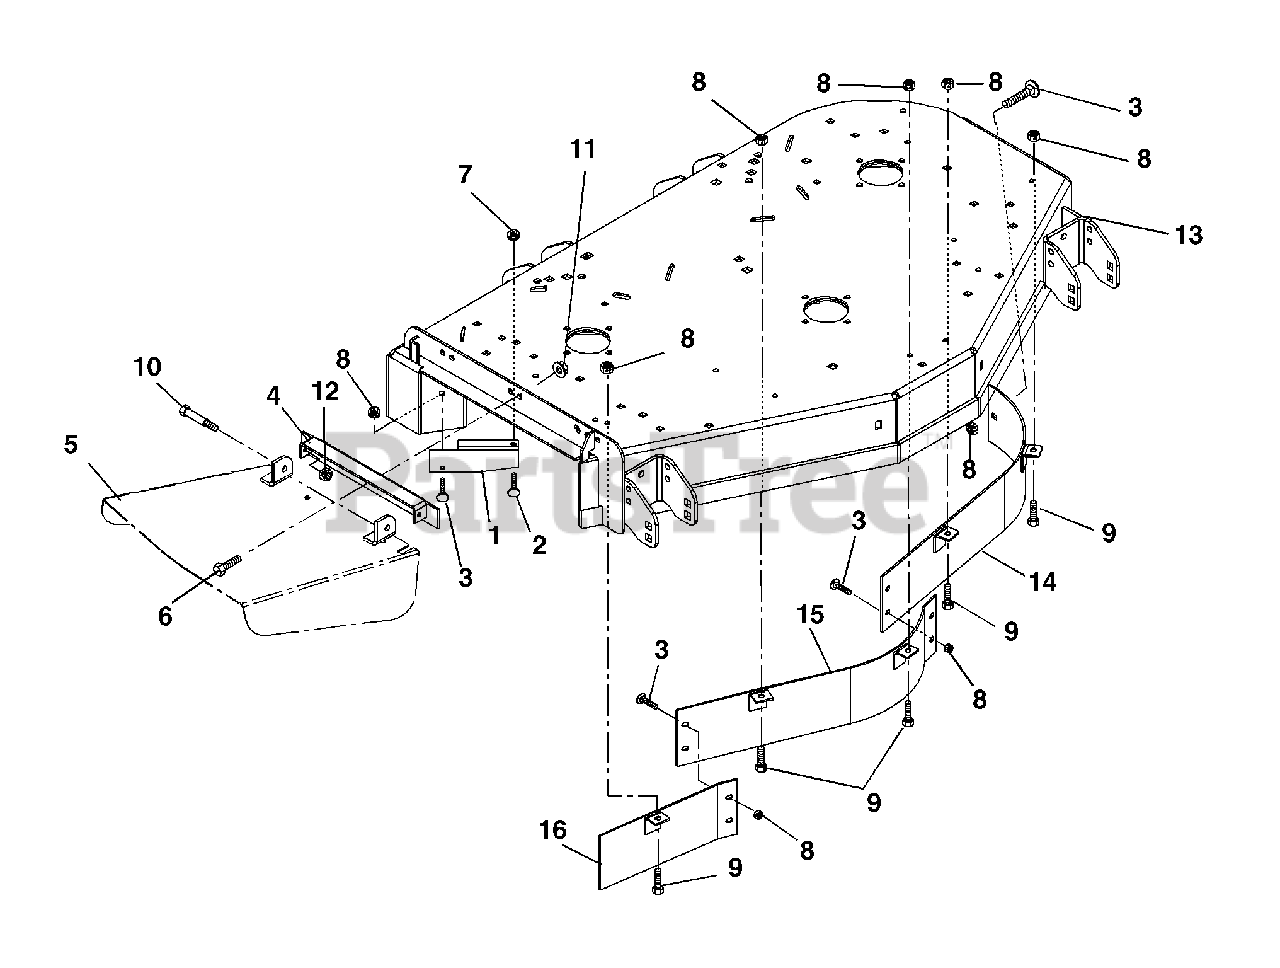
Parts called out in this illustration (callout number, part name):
1	Deflector- 60" (058, 060, 318, 319)
1	Deflector- 72" (059, 061)
2	Bolt-Round Head Square Neck .38-16 x .75 Grade 5
3	Bolt-Round Head Square Neck .31-18 x .75 Grade 5
4	Weldment, Discharge Chute Bracket
5	Chute-Discharge (058, 060, 318, 319)
5	Chute-Discharge (059, 061)
6	Bolt-Hex .38-16 x 1.00 Grade 5
7	Nut-Locking-Top-Flange .38-16
8	Nut, Locking-Top-Flange .31-18
9	Bolt, Hex .31-18 x .75 Grade 5
10	Bolt, Shoulder .38-16 x .50 Socket Head
11	Nut, Flange .375-16
12	Nut, Locking-Center .38-16
13	Weldment, 60" Mower Deck (058, 060, 318, 319)
13	Weldment, 72" Mower Deck- Float (059, 061)
14	Weldment, Upper Baffle Left 60" (058, 060, 318, 319)
14	Weldment, Baffle, Left Front-72" (059, 061)
15	Weldment, Baffle, Center Front 60" (058, 060, 318, 319))
15	Weldment, Baffle, Center Front 72" (059, 061)
16	Weldment, Baffle, Right Front 60" (058, 060, 318, 319)
16	Weldment, Baffle, Right Front 72" (059, 061)
